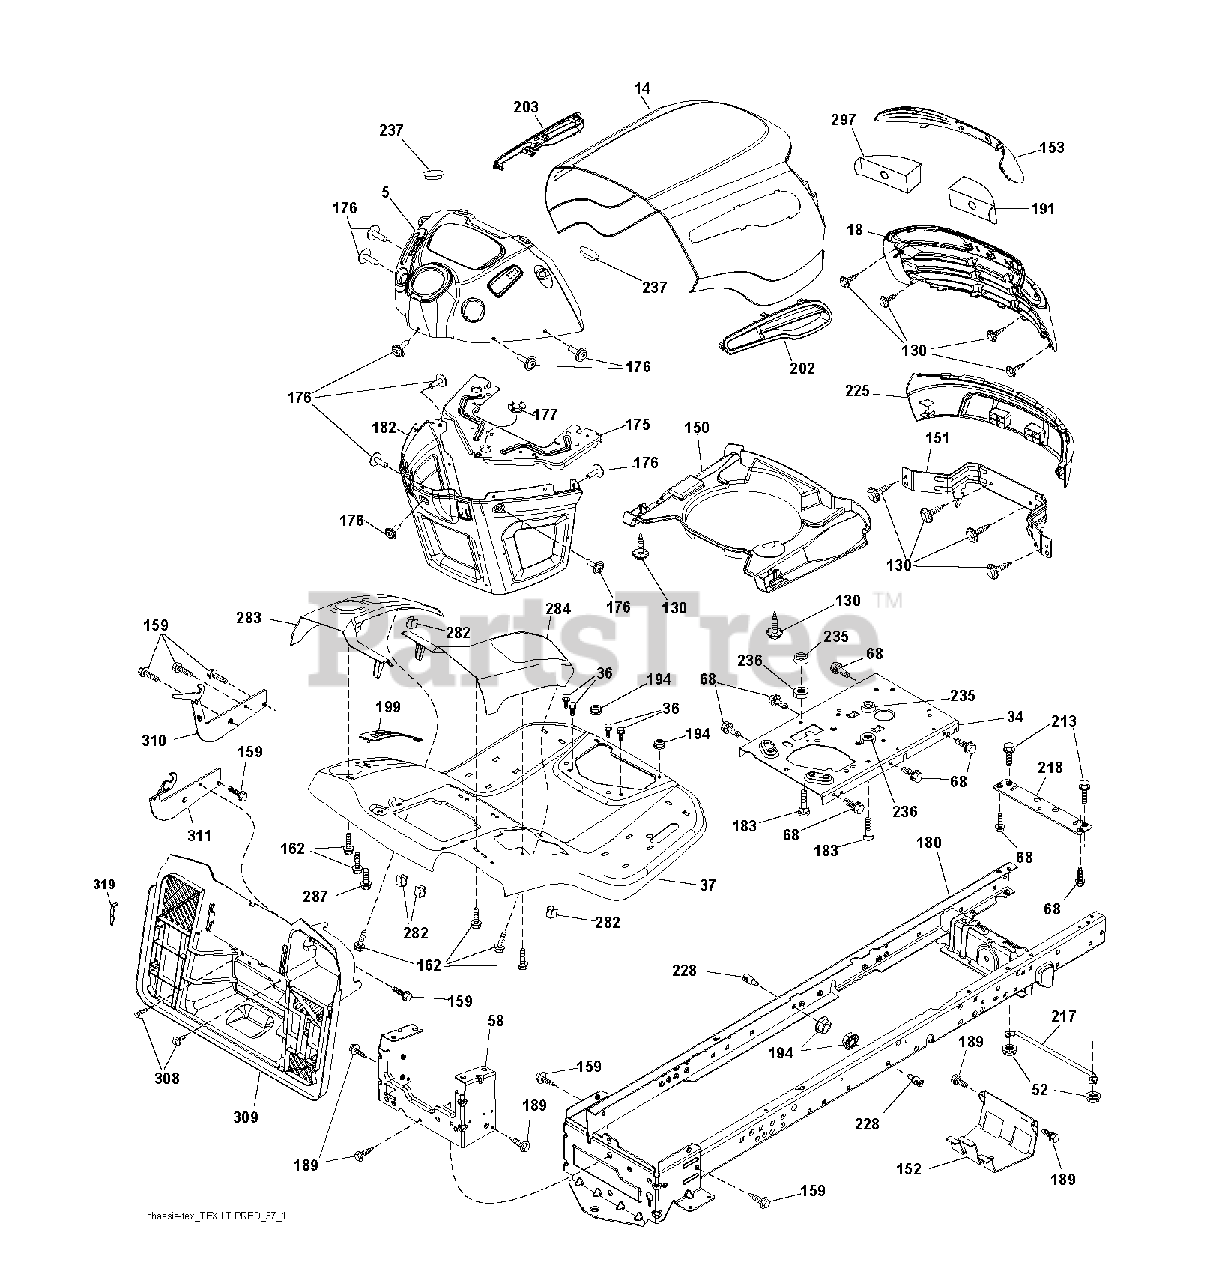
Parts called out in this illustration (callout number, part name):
34	PLATE.ENGINE.WELDED.CHASSIS
36	SCREW 5/16"
52	LOCKNUT
58	DRAWBAR UPPER 2PC SMALL FENDER
130	SCREW.#10 X 0.750.BOS THREAD
151	BRACKET.PIVOT.ALPHA.LT
152	SHIELD BROWNING
159	SCREW, 3/8-16X3/4
162	SCREW.HI-LO.CONSOLE
175	CROSSMEMBER
176	SCREW.#10-24X5/8.RN.QU
177	BUSHING STEERING
182	DASH.LWER.PREDATOR/HUSQ.LT
183	BOLT.5/16-18X1-1/4 FULL THD
189	SCREW
191	INSERT.REFLECT.PREDATOR.LT.RH
194	NUT LOCK HEX FLANGE 5/16-18
213	BOLT
217	ROD.PIVOT.HOOD
218	X-PIECE.HOOD.STOP.NON/
228	STUD.FASTNER.W/ANTI-ROTATE
235	SPACER FENDER
236	NUT.CENTERLOCK.5/16-
237	PLUG.MOUNT.CARGO.BLK
282	CLIP.RETAINER.CONSOLE.LT.HUSQ
297	REFLECTOR.INSERT.PRED.LH.LT
308	BOLT, 5/16-18 X 1 3/4
